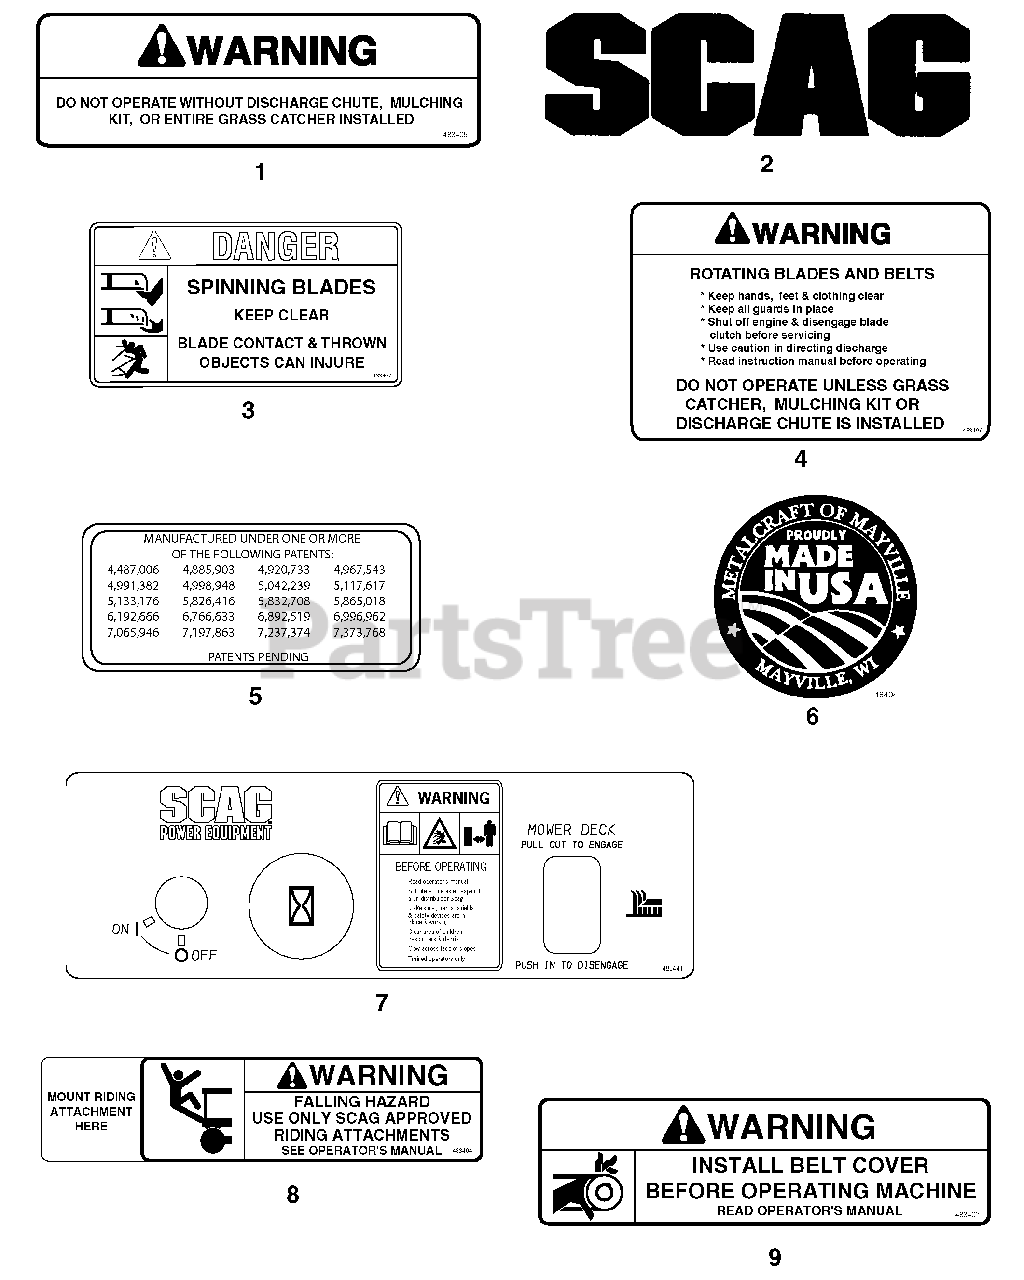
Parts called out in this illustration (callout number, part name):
1	Decal, Discharge Chute
2	Decal, Scag Logo
3	Decal, Danger-Spinning Blades
4	Decal, Warning-Rotating Blades
5	Decal, Patents
6	Decal, Metalcraft - Made in USA
7	Decal, Instrument Panel - Rear
8	Decal, Sulky Attachment
9	Decal, Belt Cover
